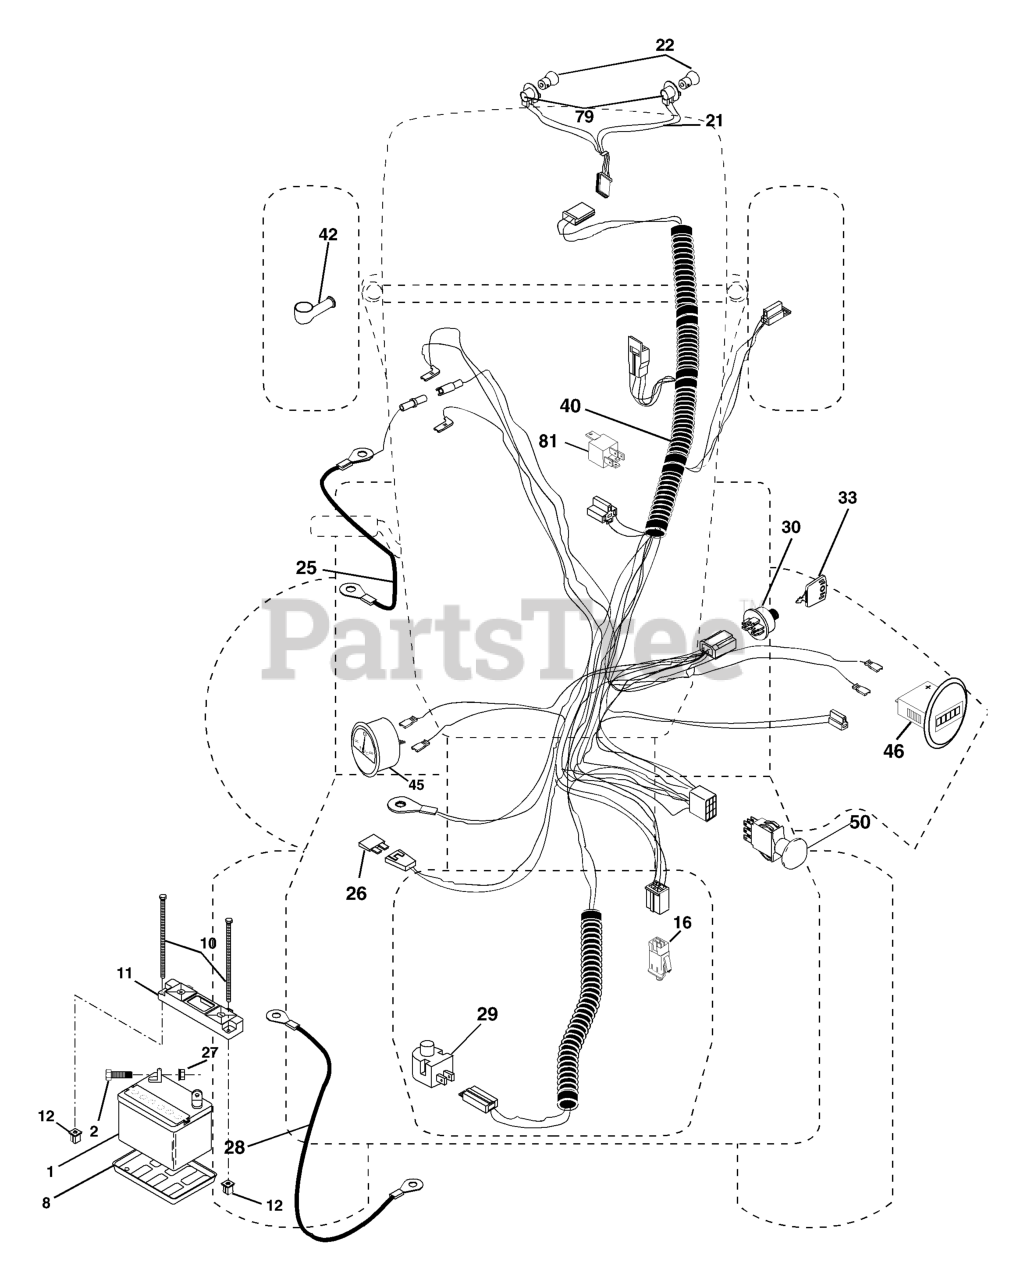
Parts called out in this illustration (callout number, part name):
1	BATTERY 12V .35 AMP
2	BOLT.HEX.1/4.X.3/4.DICHROMATE
8	BATTERY TRAY T
10	BOLT 1/4-20 X 7.5
11	BATTERY HOLDDOWN FRONT MOUNT
12	NUT, PUSH NYLON 1/4" BATTERY
16	SWITCH INTERLOOK PUSH-IN
21	HARNESS.W/LIGHT SOCKET
25	CABLE.4GA.RED.W/16GA.RED.WIRE
27	NUT
28	CABLE, GROUND
29	RP.SWITCH.PLUNGER.NC.GRAY
30	IGNITION SWITCH
33	KEY MLD GEN DELTA
40	HARNESS.IGNITION.VGT.NO.RELAY
42	COVER.TERMINAL.RED
45	RP AMMETER.ROUND.SILVER.DELTA
46	RP HOURMETER SNAP-IN
50	RP.PTO.SWITCH.8 TERMINAL.BLACK
79	BULB HOLDER ASM.
81	RELAY.ASSY.T
